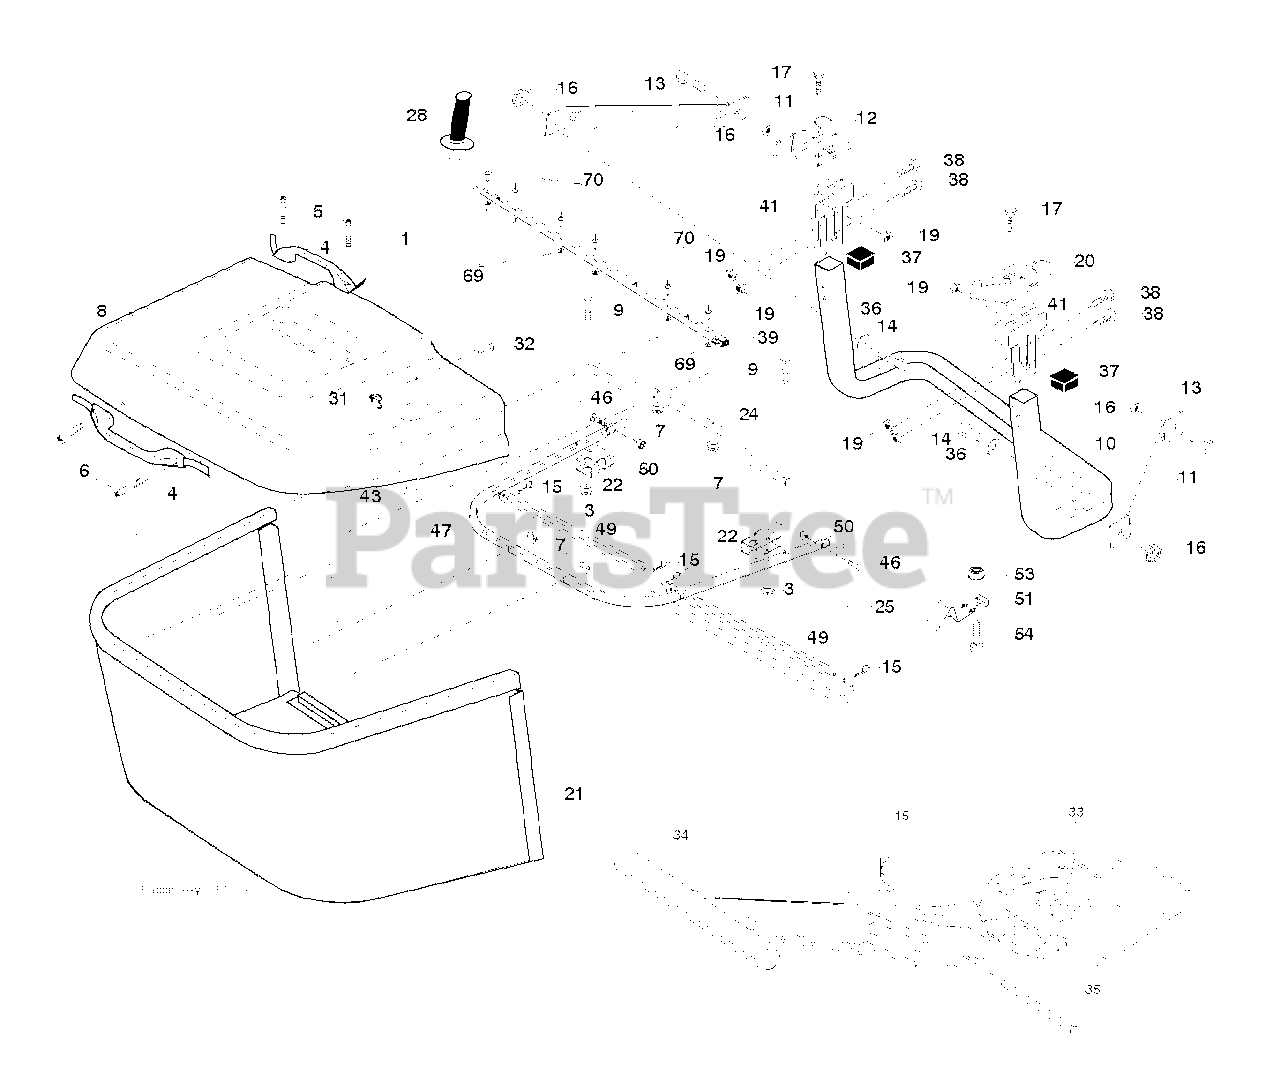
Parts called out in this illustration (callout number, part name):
1	TUBE.HANDLE.BAGGER.CRD/SRD.BLA
3	NUT T
4	HANDLE.BAGGER.W/LVRS.BLK.CRD
5	SCREW.PAN.HEAD
6	REPL BY 532 75 00-29
8	BAGGER.COVER.SEAL.ASM.
10	TUBE
11	BRACKET.SUPPORT.UPPER.BAG.CRD
12	BRKT PIVOT
14	BOLT-HEX EAK
15	Retainer Spring
16	NUT LOCK FLG 3/8-16 UNC
17	BOLT 5/16-18 X3/4 ZN/YEL GR 5
19	NUT LOCK HEX FLANGE 5/16-18
20	BRKT.PIVOT.RH.CRD
22	BRACKET.BAGGER.SD.ELECTRIC.CRD
24	TUBE.PIVOT.BAG.CRD.BLACK
25	PIPE
28	GRIP.HANDLE.BLACK
31	RETAINER CLIP
32	RIVET,DRILLED
33	MULCHING.PLUG.107.CRD.(2 2)
34	HANDLE.MULCHER.92.CRD (2 2)
36	WASHER
37	PLUG PLUG.SUPPORT.BAGGER.CRD
38	BOLT.5/16-18X2.5
39	SEAL.BAGGER.CRD
41	BRACKET.BAGGER.SD.ELECTRIC.CRD
43	PLUG, TUBING END
46	BOLT.CARRIAGE.5/16-18
47	PIPE
49	ROD
50	NUT.71038.31-18.HEX.NYLOCK
51	LATCH
53	NUT
54	BOLT
69	WASHER
70	RIVET RIVET POP
